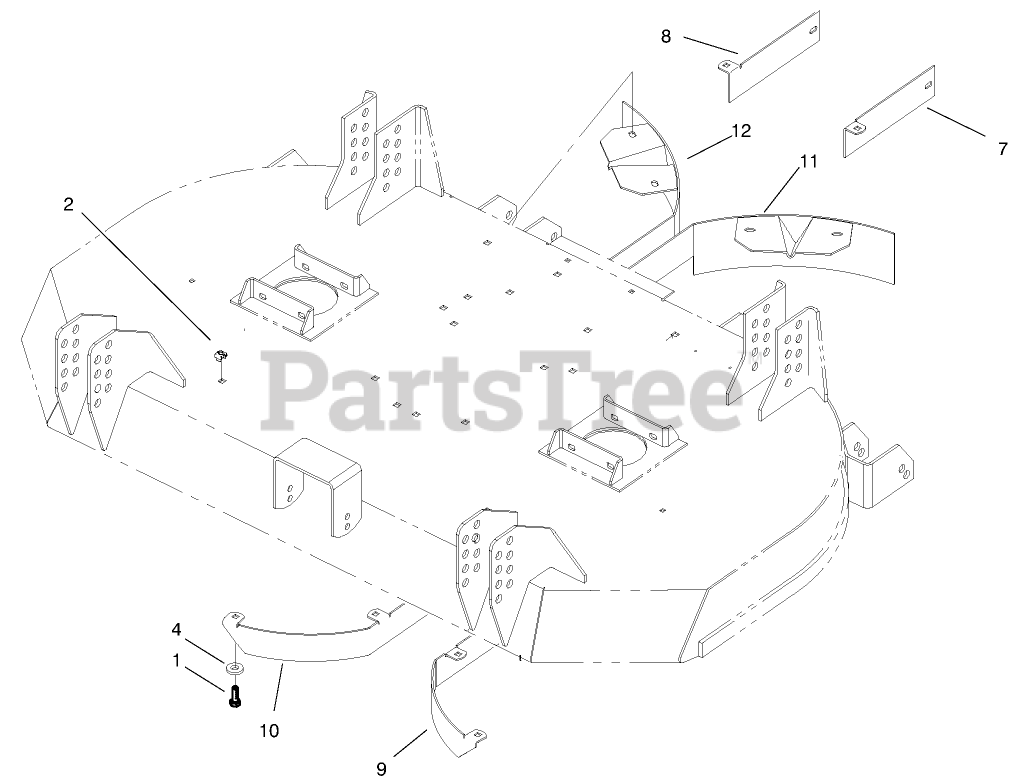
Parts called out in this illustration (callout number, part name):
1	SCREW-HH
2	NUT-RETAINED
4	WASHER-PLAIN
7	Bracket-Discharge
8	Bracket-Discharge
9	Baffle-LH
10	Baffle-RH
11	Kicker-LH
12	Kicker-RH
